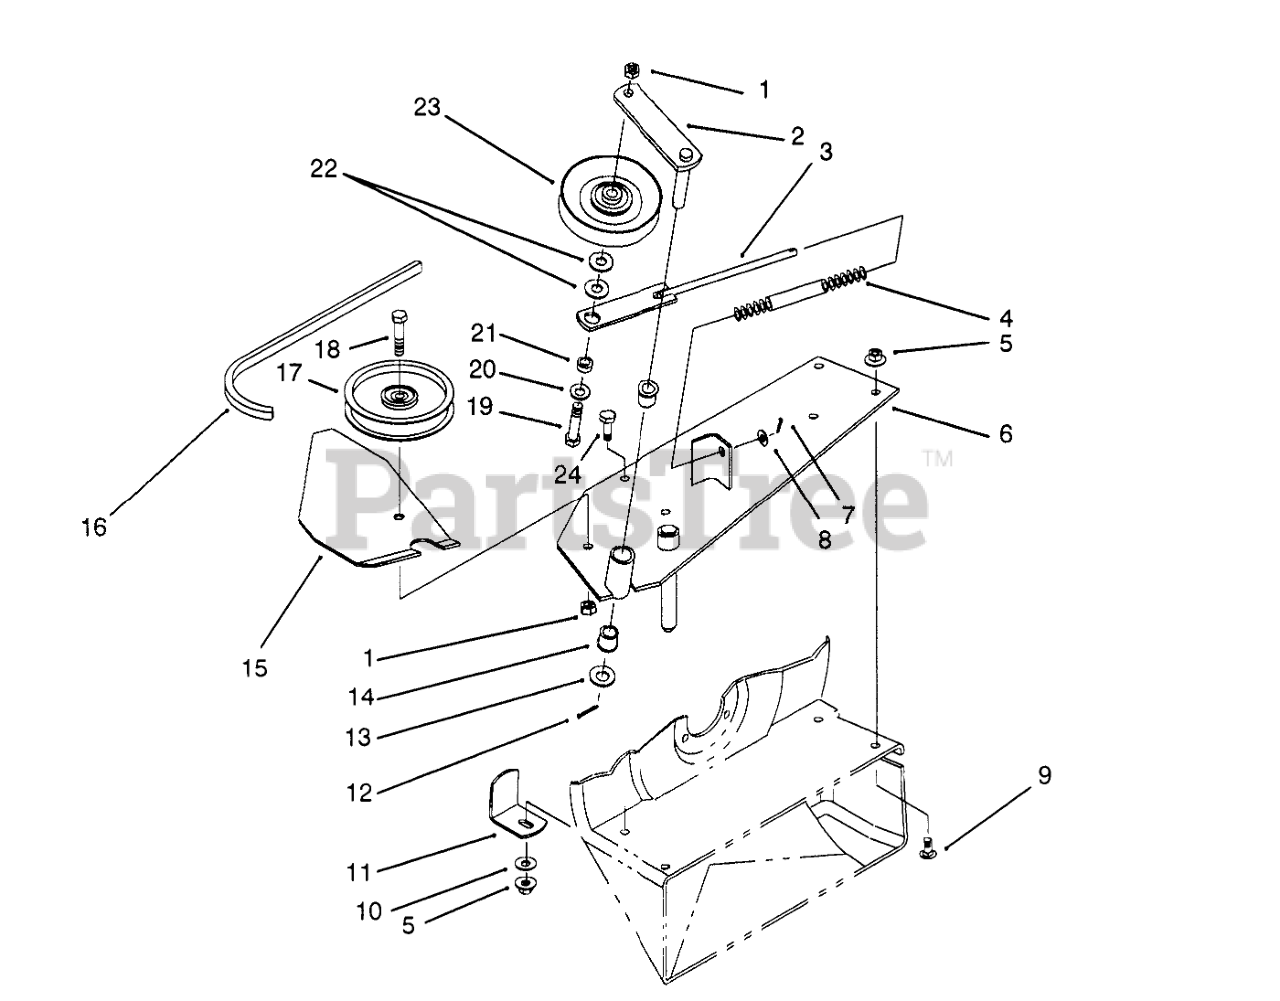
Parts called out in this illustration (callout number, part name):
1	NUT-LOCK, NI
2	IDLER ARM ASM
3	SPRING-ROD
4	SPRING-COMPRESSION
5	NUT-HF
6	BLOWER-MTG ASM
7	PIN-COTTER
8	WASHER-PLAIN
9	BOLT-CARR
10	WASHER-FLAT
11	BRACKET-SUPPORT, HOUSING
12	PIN-COTTER
13	WASHER-FLAT
14	BUSHING
15	SHIELD SUPPORT B
16	V-BELT
17	Pulley
18	SCREW-HH
19	SCREW-HH
20	WASHER-FLAT
21	SPACER
22	WASHER-FLAT
23	"V" Pulley
24	SCREW-HH
